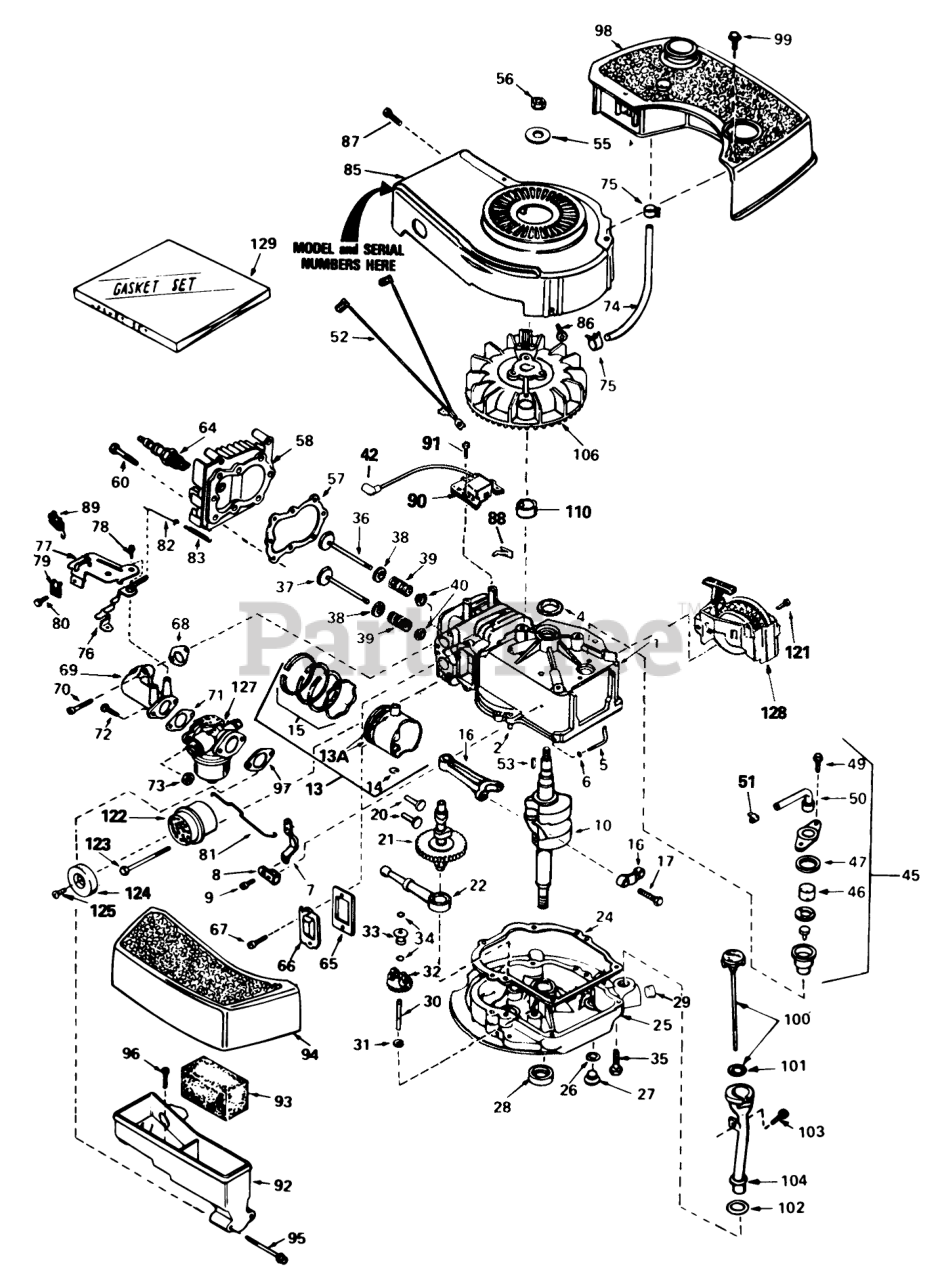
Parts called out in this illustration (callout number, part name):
1	Cylinder Assy. (Incl. #2&4)
2	Pin-Dowel
4	Seal-Oil
5	Rod, Governor (Incl. #6)
6	Washer-Flat
7	Governor Lever
8	Clamp-Lever, Governor
9	Screw
10	Crankshaft
13	Piston, Pin & Ring Assy. (Std.) (Incl. #13A, 14 & 15)
13	Piston, Pin & Ring Assy. (.010 oversize) (Incl. #13A, 14 & 15)
13	Piston, Pin & Ring Assy. (.020 oversize) (Incl. #13A, 14 & 15)
13A	Piston & Pin Assy. (Std.) (Incl. #14)
13A	Piston & Pin Assy. (.010 oversize) (Incl. #14)
13A	Piston & Pin Assy. (.020 oversize) (Incl. #14)
14	Ring-Retaining, Piston Pin
15	Ring Set (Std.)
15	Ring Set (.020" OS)
15	Ring Set (.010" OS)
16	Rod Assy., Connecting (Incl. #17)
17	Bolt-Rod, Connecting
20	Lifter-Valve
21	Camshaft(Mech.Comp. Release)
22	Oil Pump ASM
24	Gasket, Mounting
25	Flange Assy., Mounting (Incl. #26 thru 30)
26	Gasket-Oil Drain
27	Plug Oil Drain
28	Seal Oil
29	Plug-Pipe
30	Shaft-Governor
31	Washer-Flat
32	Gear Assy., Governor (Incl #31)
33	Spool-Governor
34	Ring-Retaining
35	Screw (1/4-20 x 1-1/4)
36	Valve, Intake (Std.) (Incl. #40)
36	Valve, Intake (1/32" oversize) (Incl. #40)
37	Valve, Exhaust (Std.) (Incl. #40)
37	Valve, Exhaust (1/32" oversize) (Incl. #40)
38	Cap-Upper Valve Spring
39	Spring-Valve
40	Cap-Valve, Spring
42	Cover-Spark Plug
45	Breather Assy. (Incl. #46-51)
46	Element-Breather
47	Gasket-Breather
49	Screw (10-24 x 9/16)
50	Tube, Breaker
51	Clip, Breather
52	Wire-Ground
53	Key-Flywheel
55	Washer-Belleville
56	Nut-Flywheel
57	63573 GIL 42 SNWTHW
58	Head-Cylinder
60	Screw (5/16-18x1-1/2)
64	Plug, Spark (J17LM or equiv.)
64	Plug, Spark (Champion RCJ-8)
65	Gasket-Breather
66	Cover-Valve
68	Gasket-Intake
69	Pipe, Intake (Incl. #68)
70	Screw (1/4-20 x 1)
71	Gasket-Carburetor
72	Screw (1/4-28 x 7/8)
73	Nut and Lock Washer (1/4-28)
74	Line-Fuel
75	Clamp-Line, Fuel
76	Lever Control
77	Control Assy., Speed (Incl. #76, 78 & 89)
78	Screw, Hex Washer Hd Shoulder Self-Tap
79	Conduit
80	Screw (10-32 x 3/8)
81	Link-Throttle
82	Link Governor Spring
83	Spring Governor
85	Housing-Blower
86	Screw (1/4-20x19/32)
87	Screw (10-24 x 9/16)
88	Clip, Spring
89	Terminal
90	Lamination & Coil Assy. (Solid State) (Incl. #42)
91	Screw
92	Body Air Cleaner
93	Filer, Air
94	Cove, Air Cleaner
95	Screw Fil Hd.
96	Screw, Hex Hd.
97	Gasket-Air Cleaner
98	Tank-Fuel
99	Screw (10-32 x 35/64)
100	Dipstick, Oil (Incl. #101)
103	Screw (10-32 x 1/2)
104	Tube-Oil Fill
106	Flywheel
121	Screw (1/2-20x5/8)
122	Muffler (Incl. #123)
124	Cover-Muffler
125	Screw
127	Carburetor (Incl. #71)
128	Starter-Sidemount
129	Gasket Set (Incl. items marked )
